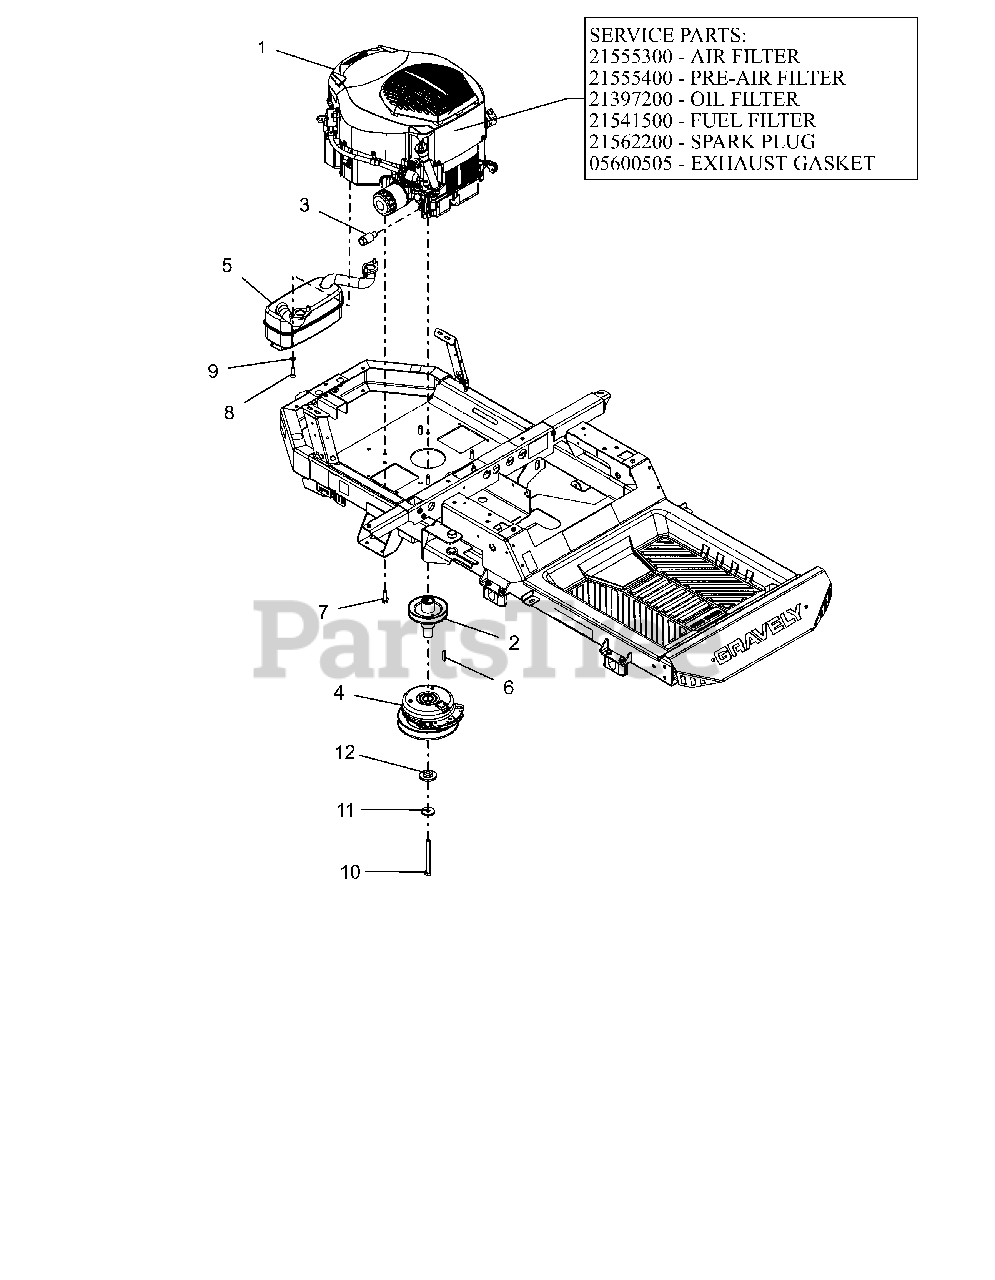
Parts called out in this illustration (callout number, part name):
1	ENGINE,KOHLER TWIN 25 PRO W/SC
1	AIR FILTER, KOHLER
1	PRE CLEANER, KOHLER
1	FILTER, OIL - KOH CV20
1	FILTER, FUEL
1	PLUG, SPARK (RFI)
1	GASKET, MUFFLER KOHLER TWIN
2	WLDMT, DRIVE SHEAVE-X
3	DRAIN, OIL
4	CLUTCH,105FTLB MONOPOLE 6.83"
5	MUFFLER - KOHLER
6	KEY-SQ .25 X 1.25 X .25 SAE
7	SCR,TAP .375-16X1.25HWH TR ZCC
8	SCR, SKH .312-18X.875 GR8 ZCC
9	WSHR,LK-REG .312X.078 ZCC
10	BLT-HEX.438-20X4.5GR8YZ NYTORQ
11	WASHER, 7/16" SPRING DISK
12	BSHG-FLG .469X1.06X.574X2.0
